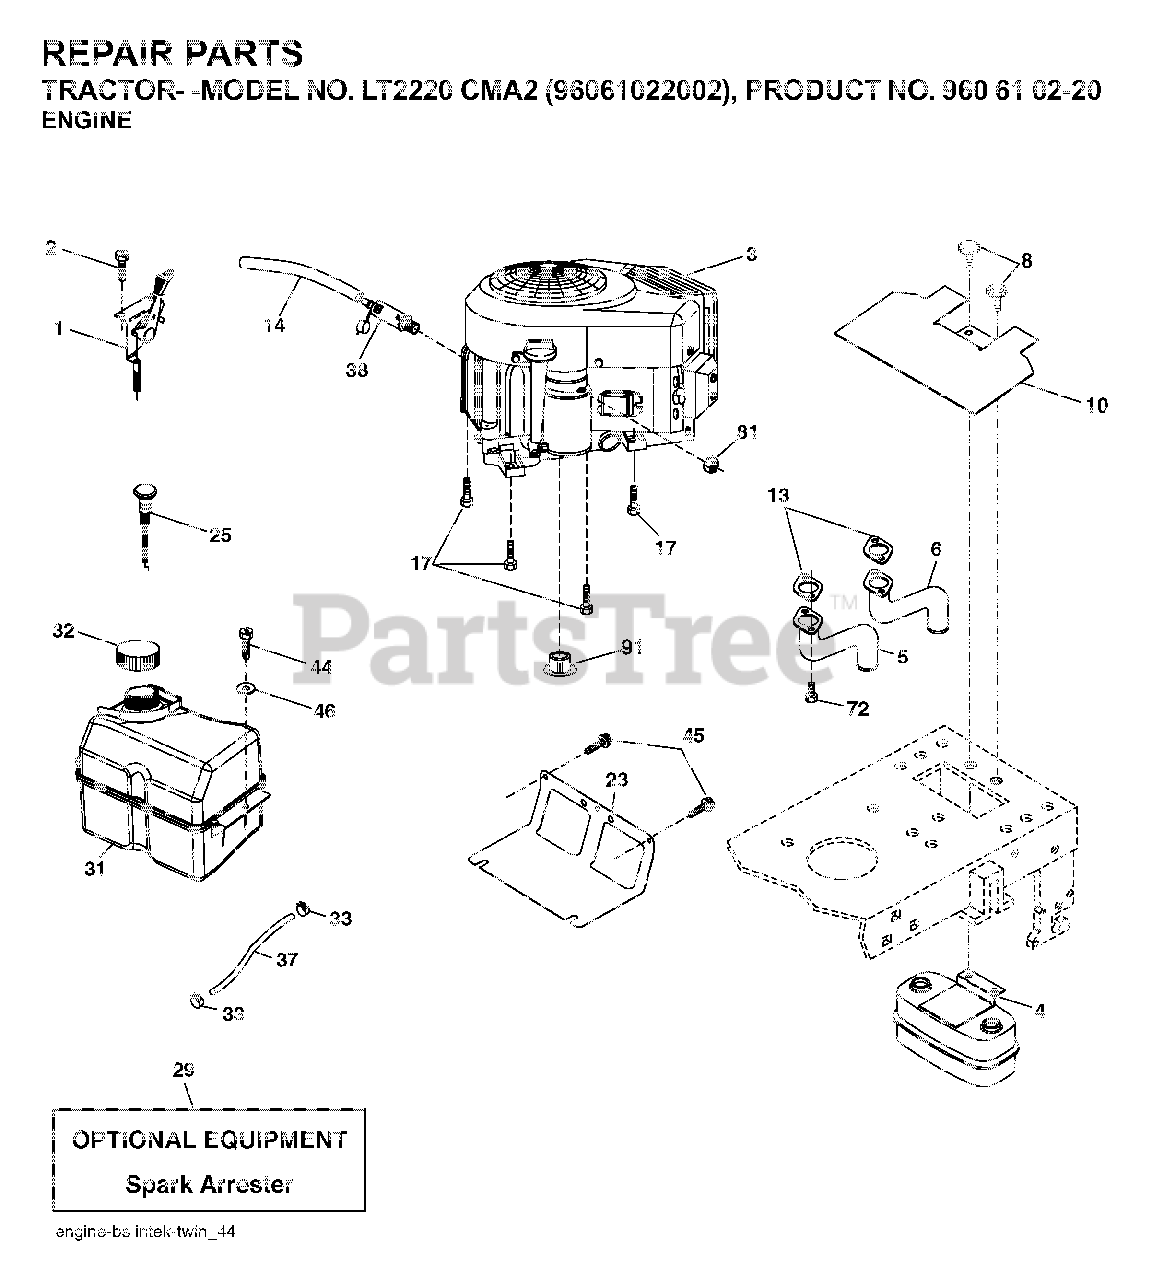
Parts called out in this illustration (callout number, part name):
1	THROTTLE CABLE
2	SCREW.#10 X 0.750.BOS THREAD
4	MUFFLER.TWIN.CYL.LOW.TONE
5	EXHAUST TUBE RH
6	TUBE MANIFOLD LH
8	BOLT, 5/16-18 X 1 3/4
10	RP SHIELD HEAT MUFFLER
13	GASKET.MUFFLER
14	TUBE, DRAIN OIL ASM.
17	SCREW.3/8-16
23	SHEILD.BROWNING.DBR.GUARD
25	CONTROL CHOKE
29	ARRESTER SPARK (OPTIONAL)
32	FUEL CAP
33	HOSE CLAMP
37	LINE.FUEL.20
38	PLUG DRAIN OIL EASY
44	SCREW HEXWSHR 1/4-20X3/4
45	SCREW, 3/8-16X3/4
72	SCREW.SOCKET.HEAD.5/16-18
81	NUT
